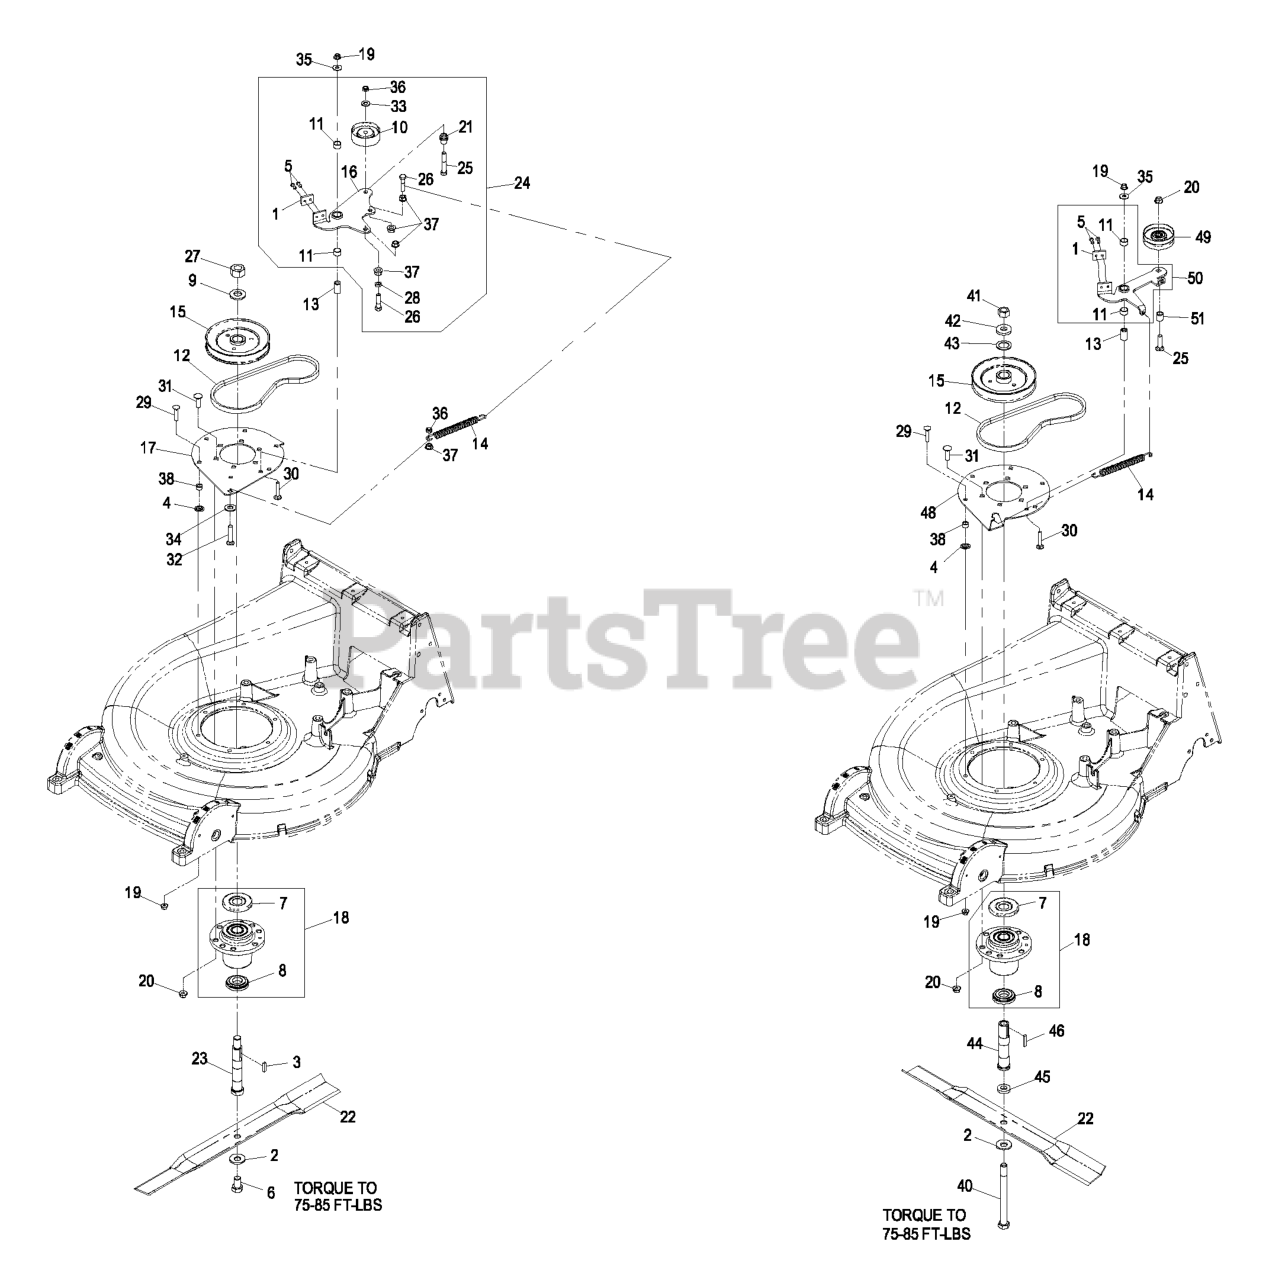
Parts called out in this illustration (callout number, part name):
1	PAD-BRAKE
2	WASHER-SPRING
3	KEY-RECTANGLE
4	RING-RETAINING
5	RIVET-POP
6	SCREW-CAP
7	GUARD-BEARING, TOP
8	SPACER-GUARD, BOTTOM
10	PULLEY-IDLER
11	BEARING
13	BUSHING-ARM, IDLER
14	SPRING-BRAKE
15	SHEAVE-SPINDLE
16	ARM-IDLER
17	PLATE-ADAPTER, HOUSING
18	KIT, CUTTER HOUSING
19	NUT-HF, NI
20	NUT-HF, NI
21	BUSHING-LATCH, SEAT
23	SHAFT-SPINDLE
24	ASM,IDLER ARM
25	SCREW-HH
26	SCREW-HH
28	NUT-JAM
29	BOLT-CARR
30	BOLT-CAR
31	Bolt-Carriage 3/8-16 X 1 1/4
32	SCREW-HH
33	WASHER-FLAT
34	WASHER-FLAT
35	WASHER-FLAT
37	NUT-HHF, WHIZ
38	SPACER
39	ASM,CUTTER HOUSING COMPLE
40	SCREW-HH YZ
41	NUT-HEX
42	WASHER-RETAINER, SHEAVE
43	WASHER-SPACER
44	TUBE-SPINDLE, SHORT
47	ASM,CUTTER HOUSING COMPLE
48	PLATE,CUTTER HOUSING
